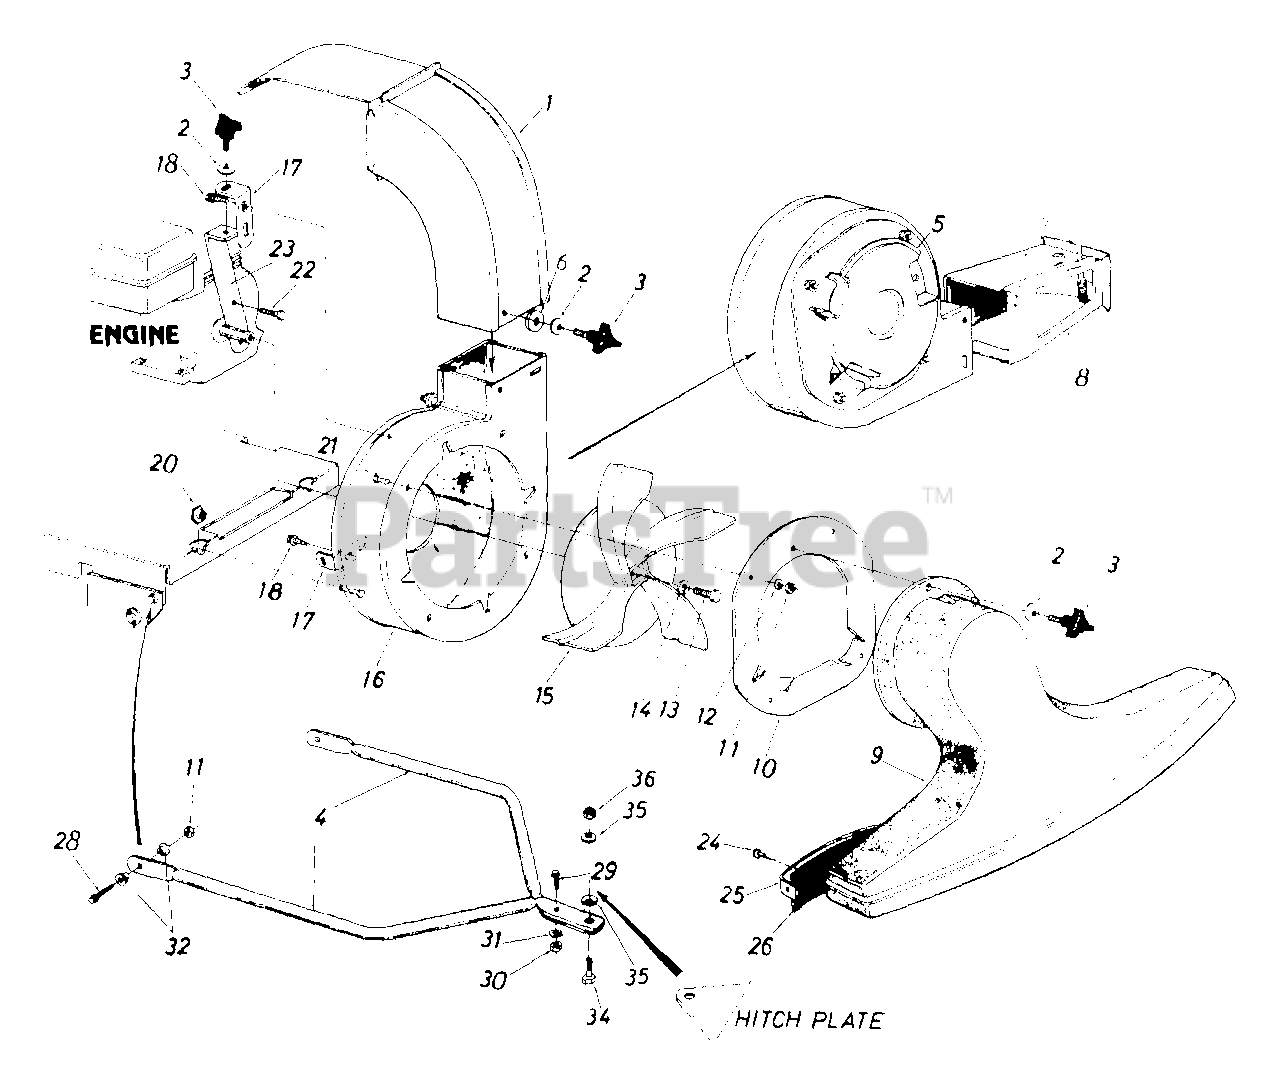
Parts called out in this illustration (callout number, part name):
3	Hand Knob
6	Fl-Wash. .344" I.D. x 1.125" O.D.
10	Nozzle Plate Ass'y.
11	Hex Nut 5/16-18 Thd.
12	L-Wash. 5/16" I.D.
13	Hex Bolt 3/8-24 x 1.25" Lg.
14	L-Wash. 3/8" I.D. H.D.
15	Air Vane Plate Ass'y.
20	Hex Shoulder Nut.50 I.D.
21	Carriage Bolt 5/16-18 x .62"
22	Hex Locking Bolt 5/16-24 x .75" Lg.
28	Hex Bolt 5/16-18 x 1.00" Lg.
29	Truss Mach. Scr. 1/4-20 x .75"
30	Hex Nut 1/4-20 Thd.
31	L-Wash. 1/4" I.D.
32	Shoulder Spacer
34	Shld. Bolt .496 Dia.
35	Belleville Wash. .39" I.D. x 1.12" O.D.
36	Hex Jam L-Nut 3/8-26 Thd.
